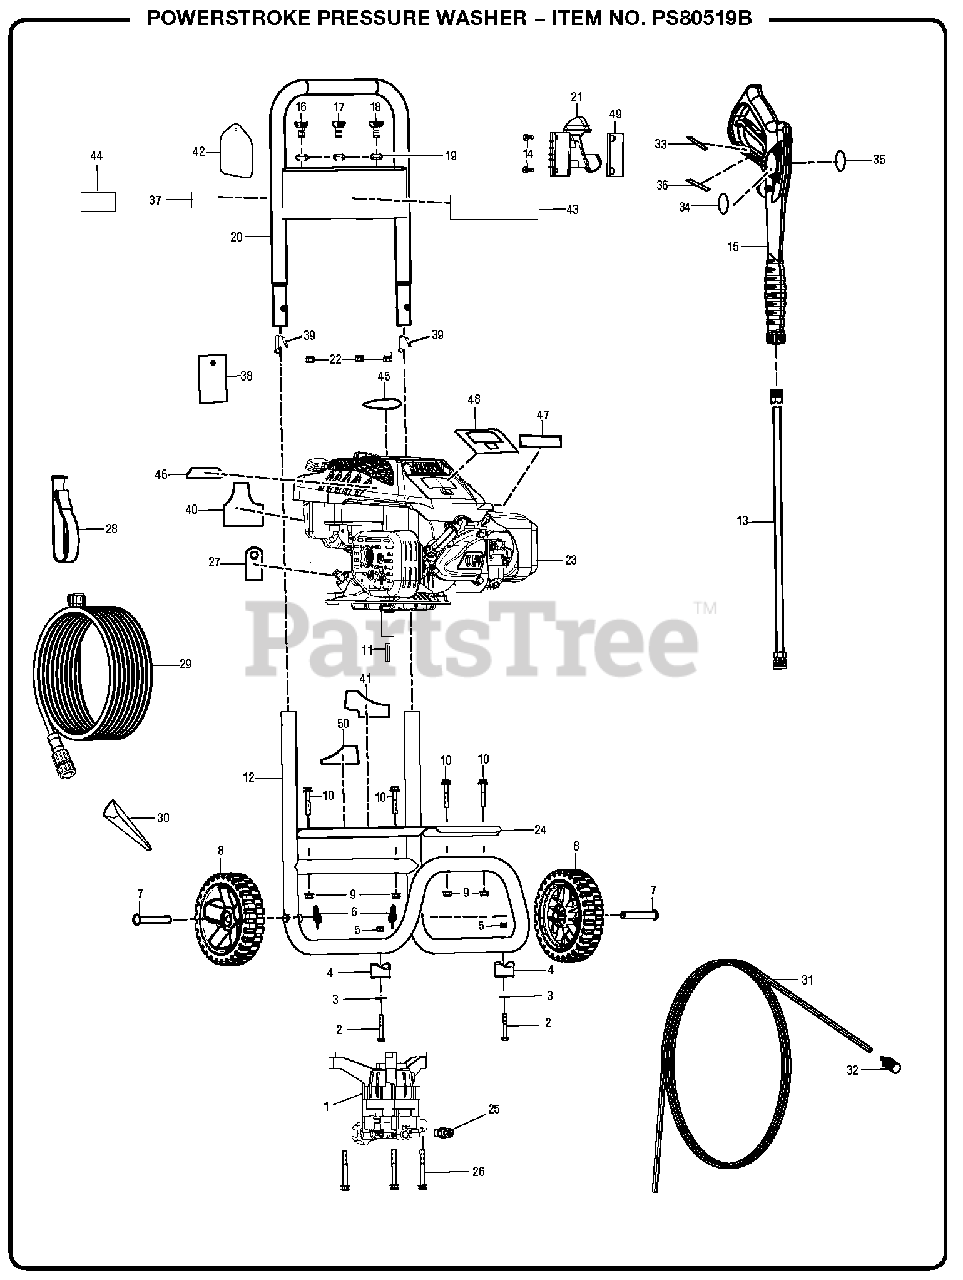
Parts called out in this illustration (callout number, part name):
2	Screw (1/4-20 x 2 in., T30 Torx Hd.)
3	Washer (1/4 in.)
5	Lock Nut (1/4-20)
6	Axle Clip
9	Hex Nut (M8)
10	Bolt (M8 x 45 mm Flange Hd.)
11	Output Shaft Key
12	Main Frame Assembly
13	Extension Wand
14	Screw (M6 x 20 mm, Phillips Hd.)
15	Trigger Handle w/Logo
16	Soap Nozzle
17	25deg Nozzle
18	40deg Nozzle
19	Nozzle Holder
20	Handle Assembly
21	Wand Holder
22	Lock Nut (M8)
23	Engine
24	Engine Plate
25	Thermal Release Valve
26	Bolt (M8 x 70, Flange Hd)
27	Add Oil Hang tag
28	Hose Holder Strap
29	Hose (25 ft.)
31	Chemical Siphon Tube
32	Chemical Siphon Filter
33	Trigger Handle Warning Label (Fr/Sp)
34	Trigger Handle Logo Label
35	Trigger Handle Warning Label (Eng)
36	Trigger Handle Rating Label
37	Quick Start Label
38	Danger Hang tag
39	Spring Clip
40	E85 Label
41	Danger Label
42	Nozzle Hang Tag
43	Performance Label
44	Inquiries Label
45	Logo Label
46	Hot Surface Label
47	Choke Label
48	On/Off Label
49	Rubber Gasket
50	Add Oil Label
